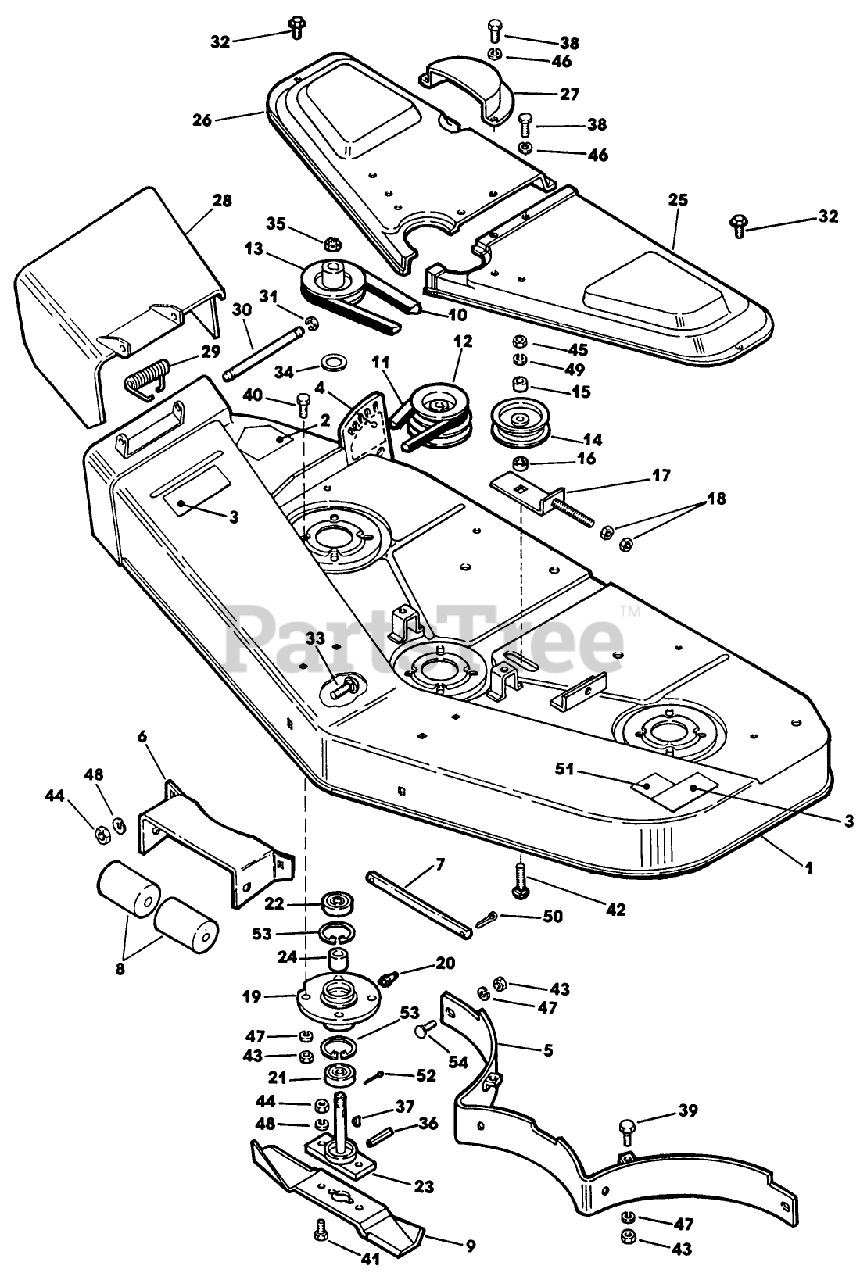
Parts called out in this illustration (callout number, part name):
3	DECAL
7	SHAFT
8	ROLLER
10	V-BELT (DECK)
14	PULLEY - IDLER
15	SPACER
19	HOUSING,SPINDLE S
23	SPINDLE ASSEMBLY *N/P
26	COVER AY - RH
30	SHAFT - CHUTE
31	E-RING
32	SCREW-THREAD FRMG
33	BOLT - CARRIAGE
34	SPACER
35	NUT-BLADE SPINDLE
38	SCREW-HH
39	SCREW - HEX
40	SCREW
42	BOLT
43	NUT SS
44	NUT
45	NUT - HEX JAM
48	WASHER
49	WASHER
